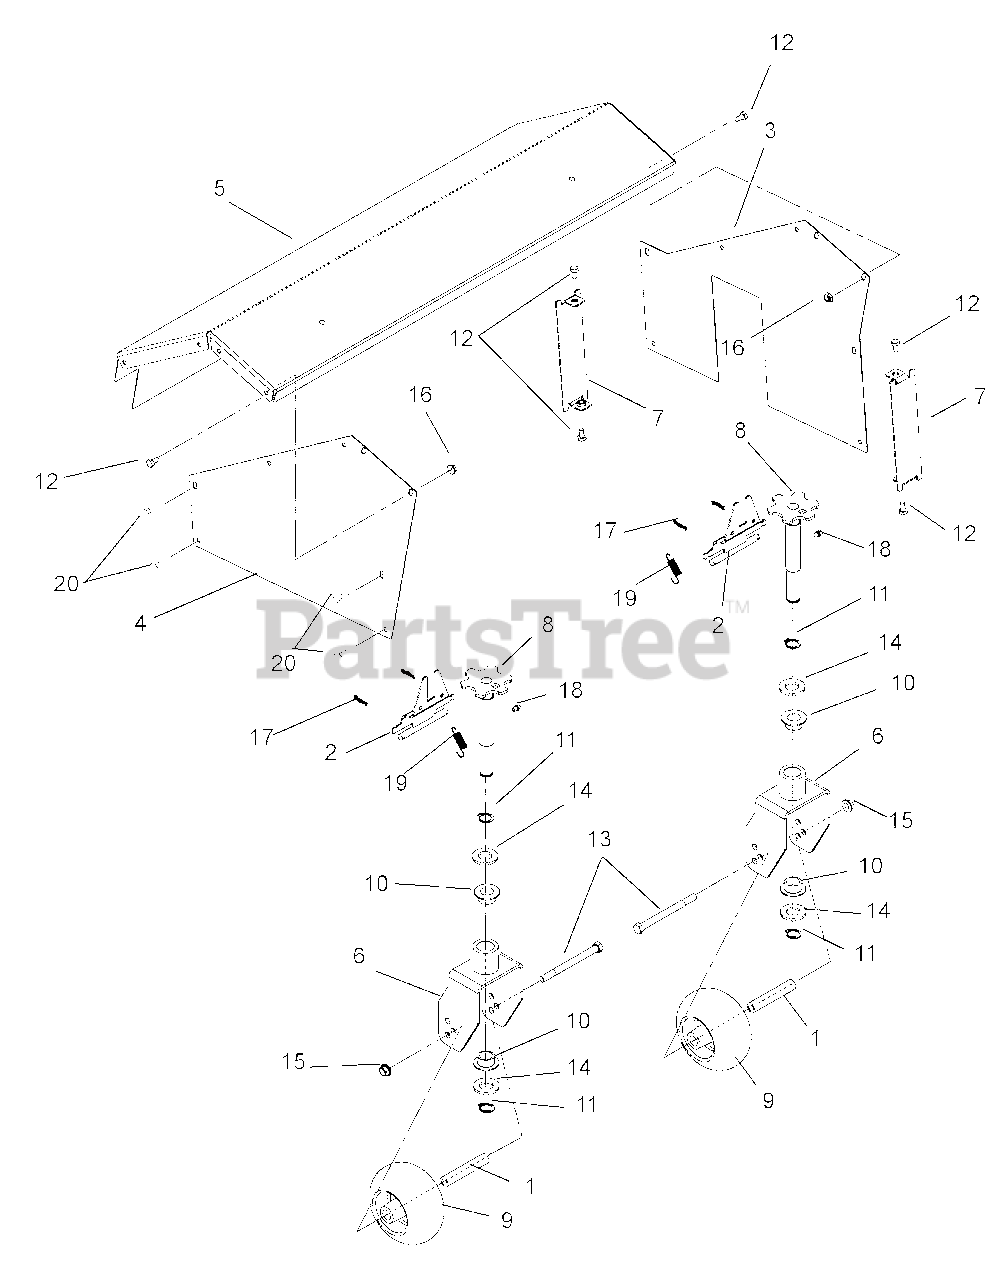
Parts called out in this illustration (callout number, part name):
1	SPACER, CASTER WHEEL
2	LOCK,CASTER HEIGHT
3	COVER,LH SIDE BRUSH
4	COVER,RH SIDE BRUSH
5	COVER WITH DECALS, 28"BRUSH
6	CASTER FORK, BRUSH
7	COVER,END
8	HEIGHT ADJUSTER, CASTER
9	WHEEL, ANTI SCALP
10	BSHG-FLG .762X1.0X.580X1.48 NY
11	RG-RTNG-EXT .689X.078
12	@BLT-HEX .25-20X.50 GR5 YWZC
13	@BLT-HEX .38-16X4.50 GR5 YWZC
14	@WSHR-FL-STL.812X1.50X.135YWZC
15	@NUT-LK-TOP-FLG .38-16 YWZC
16	@NUT-LK-TOP-FLG .25-20 YWZC
17	PIN-HAIR, ENDRIES #25 YWZC
18	FTG-LUBE .25-28X.256 YWZC
19	SPRING-EXT .047 X .438 X 1.85
20	SCR-TAP .25-20X.50 HWH TR YWZ
